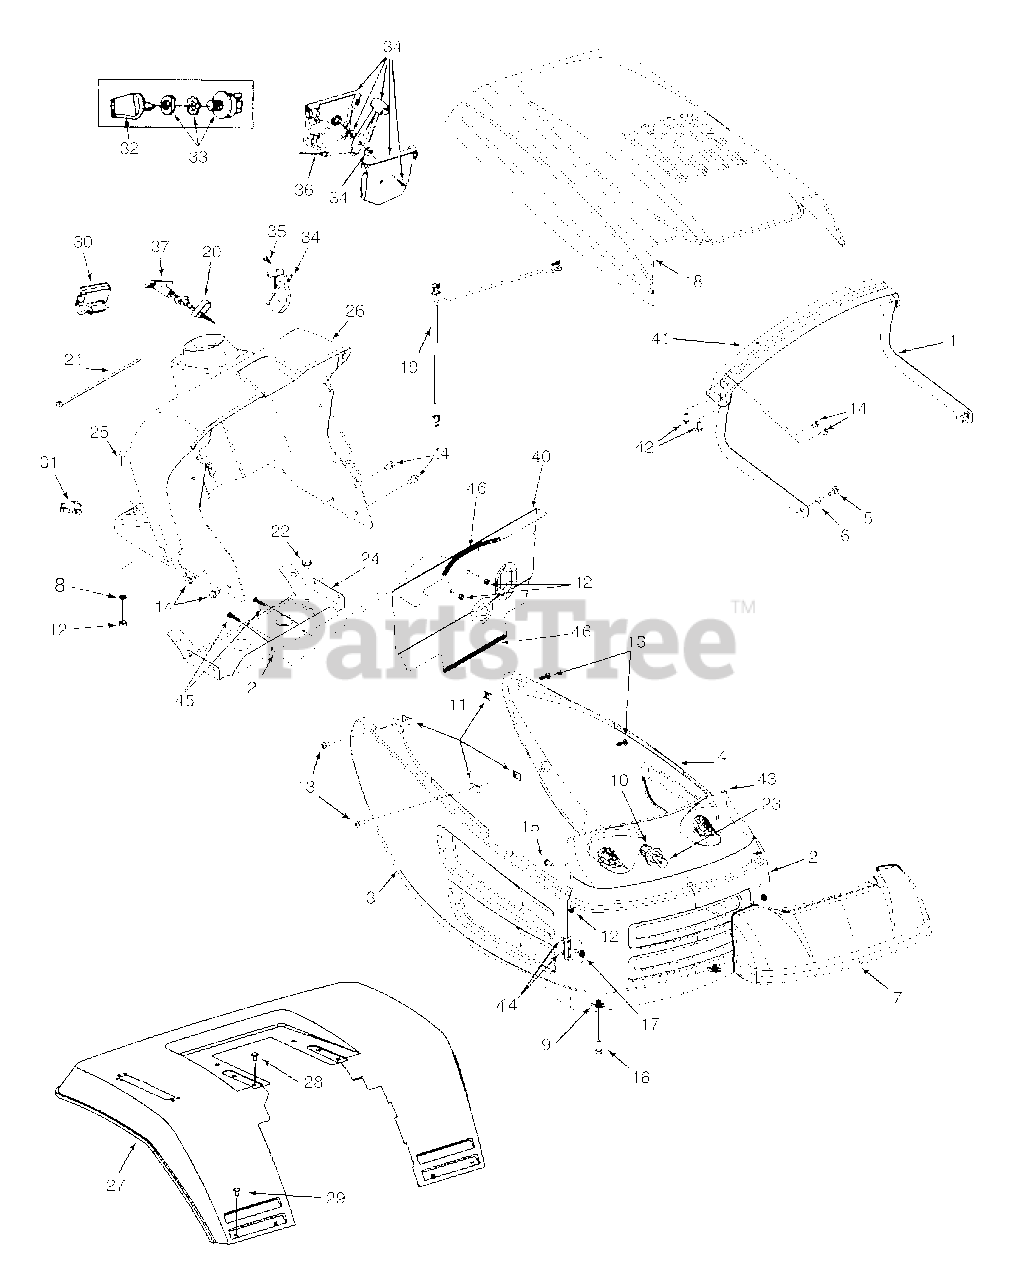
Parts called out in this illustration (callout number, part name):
6	Spr. Wash. .39" I.D. x .62" O.D.
7	Lens
8	Retainer Nut
9	U - Nut 5/16-18 Thd
10	Socket
11	Tinn. Nut 1/4-20 Thd.
12	Hex Sems Nut 1/4-20 Thd.
13	Pan Hd. Mach. Scr. 1/4-20 x .75" Lg.
14	Hex Wash. Hd. TT-Tap Scr. 1/4-20 x .5"
15	Hex Bolt
16	Hex Bolt 5/16-18 x .1" Lg. (Gr.5)
19	Headlight Harness
20	Choke Retainer
21	Cable Tie
22	Hex Wash. Hd. Tap Scr. 5/16-18 x .5"
23	Lamp
26	Dash Panel
29	Truss Mach. Scr. 1/4-20 x .5" Lg.
30	Ammeter
31	Light Switch
32	Ignition Key
33	Ignition Switch
34	Throttle Box Assembly
35	Truss Mach. AB-Tap Scr. #10 x .5"
36	Throttle Control Wire 18.5" Lg.
37	Choke Control 20" Lg.
43	Retainer Nut
44	Hex Wash. AB-Tap Scr. 1/4-14 x .625"
45	Pan Hd. Scr. 1/4-20 x 1" Lg.
46	Trim Strip
